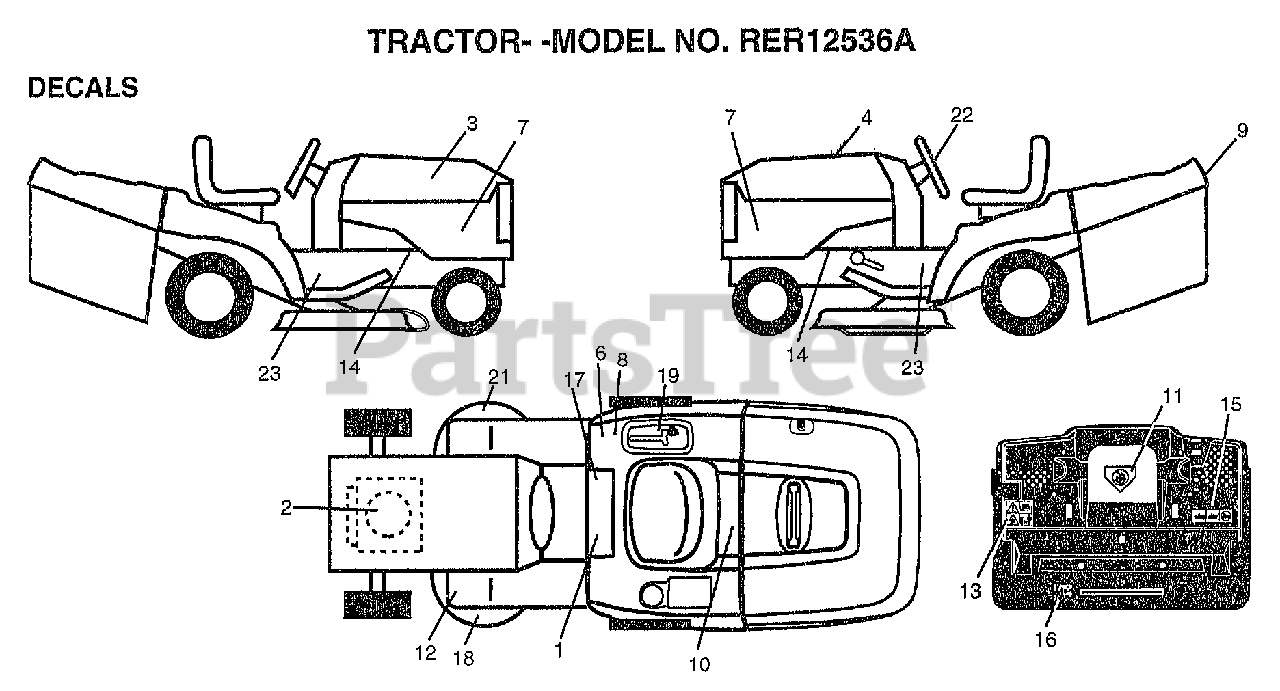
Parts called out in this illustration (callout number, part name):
1	DECAL.READ.O.MANU
2	DECAL.ENG.B&S
3	DECAL HOOD RH
4	DECAL HOOD LH
5	DECAL.CONSOLE.6SP.CRD
8	DECAL.EURO.ST.CE.
9	FENDER DECAL
10	DECAL.BATRY.3-3908
11	DECAL.DANGER.CUTF
12	DECAL-BRAKE/CLUTC
13	DECAL, WARN BACK PLATE
14	"DECAL CHASSIS,HOT"
15	DECAL, OPER BAG
16	DECAL.DRAWBAR.LDL
17	DECAL BRAK PARK
19	DECAL.CONSOLE.6SP.CRD
21	DECAL.DECK.HEX.BELT
22	"DECAL,STR WHL"
23	DECAL.CHASSIS.RALLY
